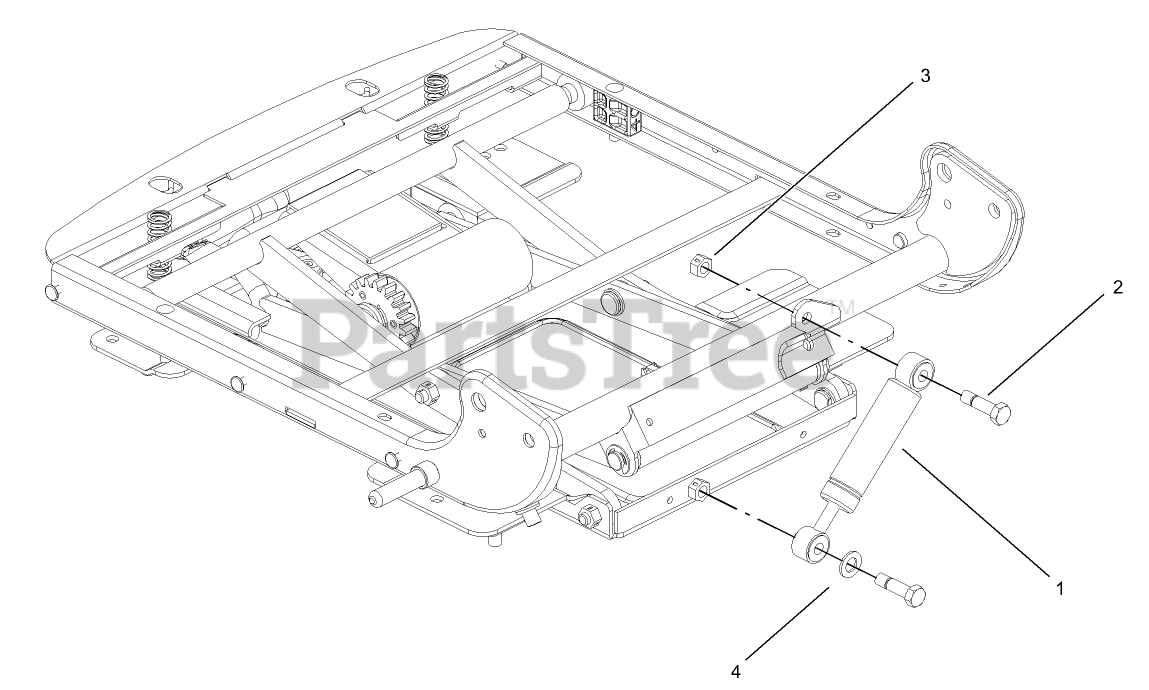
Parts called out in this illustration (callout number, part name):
1	Damper
2	Bolt
3	Nut
4	Washer
